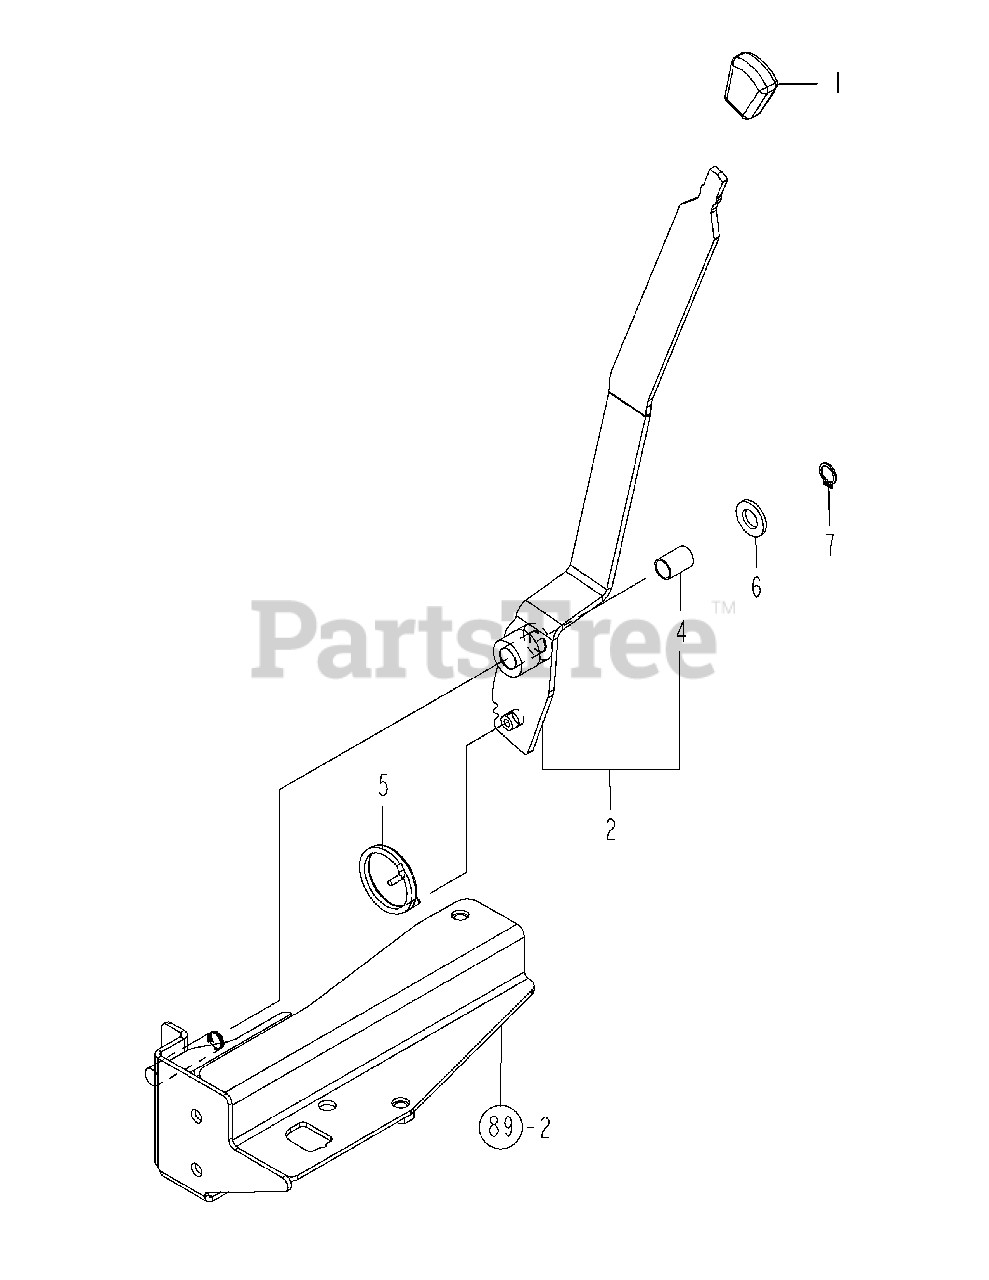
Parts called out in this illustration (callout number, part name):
1	KNOB, PARK BRAKE
2	LEVER ASY, PARKING
4	BEARING, 12 X 20
